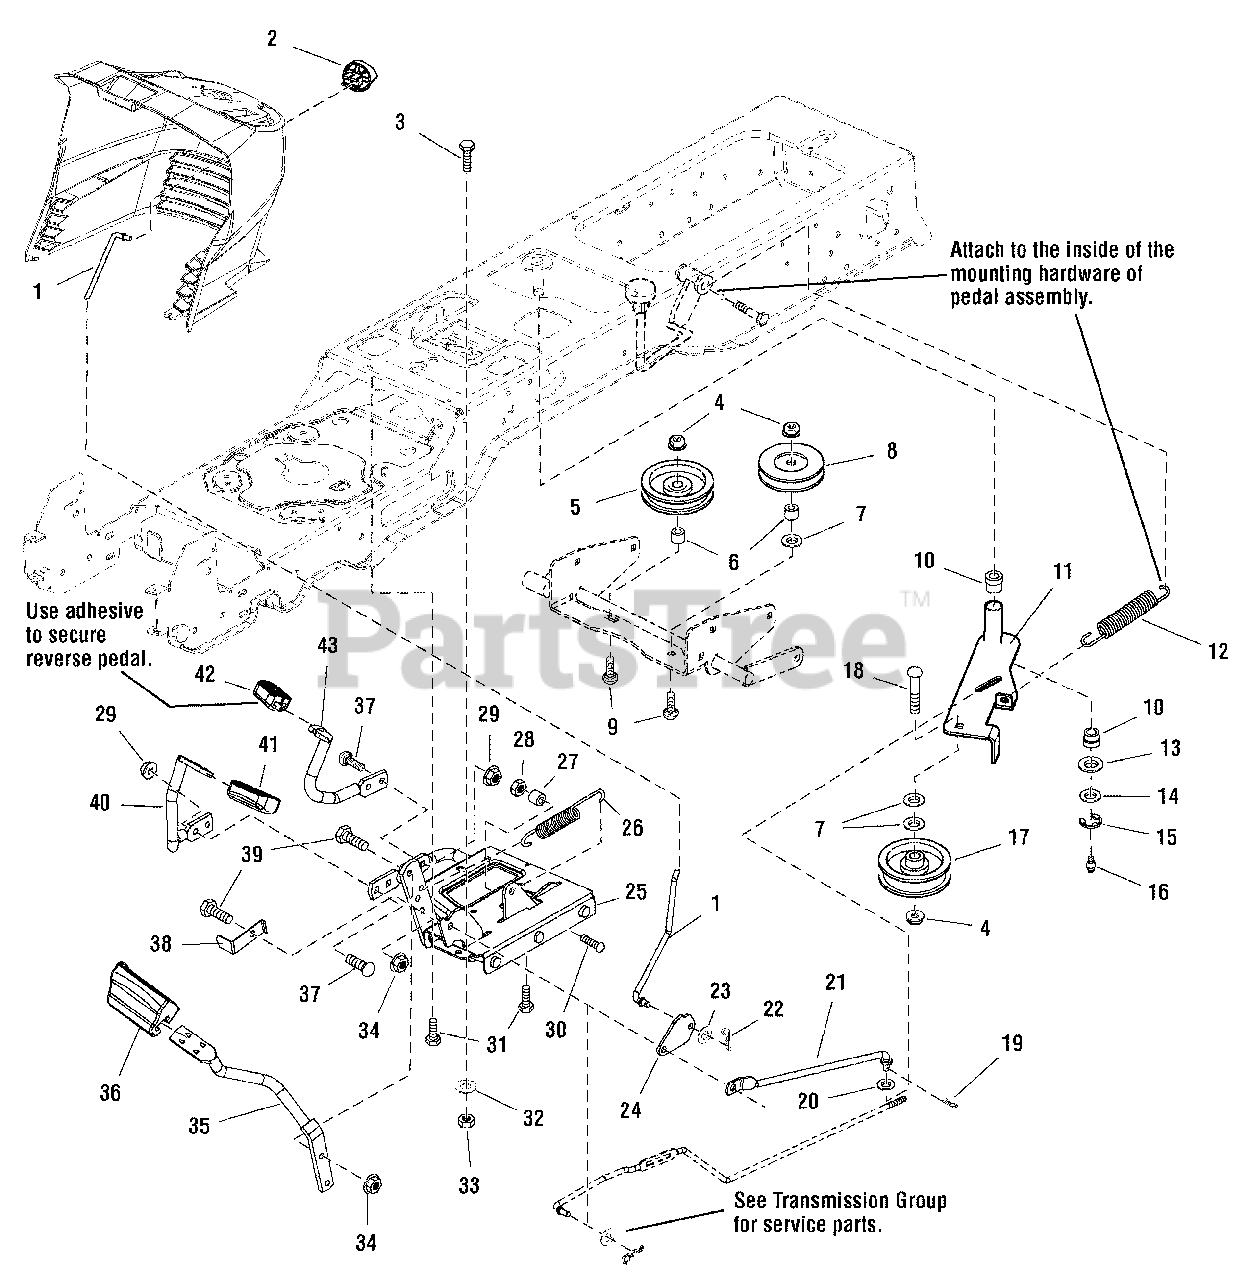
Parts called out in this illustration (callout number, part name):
1	ROD, Brake
2	KNOB, Push On, Red
3	CAPSCREW, Hex Head Flange Lock, 5/16-18 x 3/4
4	NUT, Hex Flange, 3/8-16 ESNA
5	PULLEY ASSEMBLY, 3 OD, W/Bearing
7	WASHER, 3/8
8	PULLEY, Idler 4 OD
9	CARRIAGE BOLT, 3/8-16 x 2 G5
11	ARM & HUB ASSEMBLY, Idler
12	SPRING, Extension
13	WASHER, Plain, 21/32
14	WASHER, 5/8
15	RING, Clipring
16	FITTING, Lube, 1/4 Ball Check
17	PULLEY, Idler 3-1/4 OD
18	CARRIAGE BOLT, 3/8-16 x 2 G5
19	PIN, Cotter
20	WASHER
21	ROD, Brake (Flat Ends)
22	PIN, Quick
23	WASHER, 5/16
24	LATCH, Brake
25	CONTROL ASSEMBLY, Foot Pedal
26	SPRING, Extension, 5/8 x 6-5/8
27	CAM, Roller
28	NUT, Hex Lock ESNA, 1/4-20
29	NUT, Hex KEPS, 5/16-18
30	CARRIAGE BOLT, 1/4-20 x 1-1/4
31	CAPSCREW, Hex head Washer Taptite, 5/16-18 x 3/4
32	WASHER
33	NUT, Hex Lock ESNA, 5/16-18
34	NUT, Hex Flange Lock, 5/16-18
35	PEDAL, Brake
36	PAD, Brake Pedal
37	CARRIAGE BOLT, 5/16-18 x 7/8
38	ACTUATOR, Switch
39	CAPSCREW, Hex Head, 5/16-18 x 1
40	PEDAL, Forward
41	PAD, Foot Pedal Forward
42	PAD, Foot Pedal Reverse
43	PEDAL, Reverse
